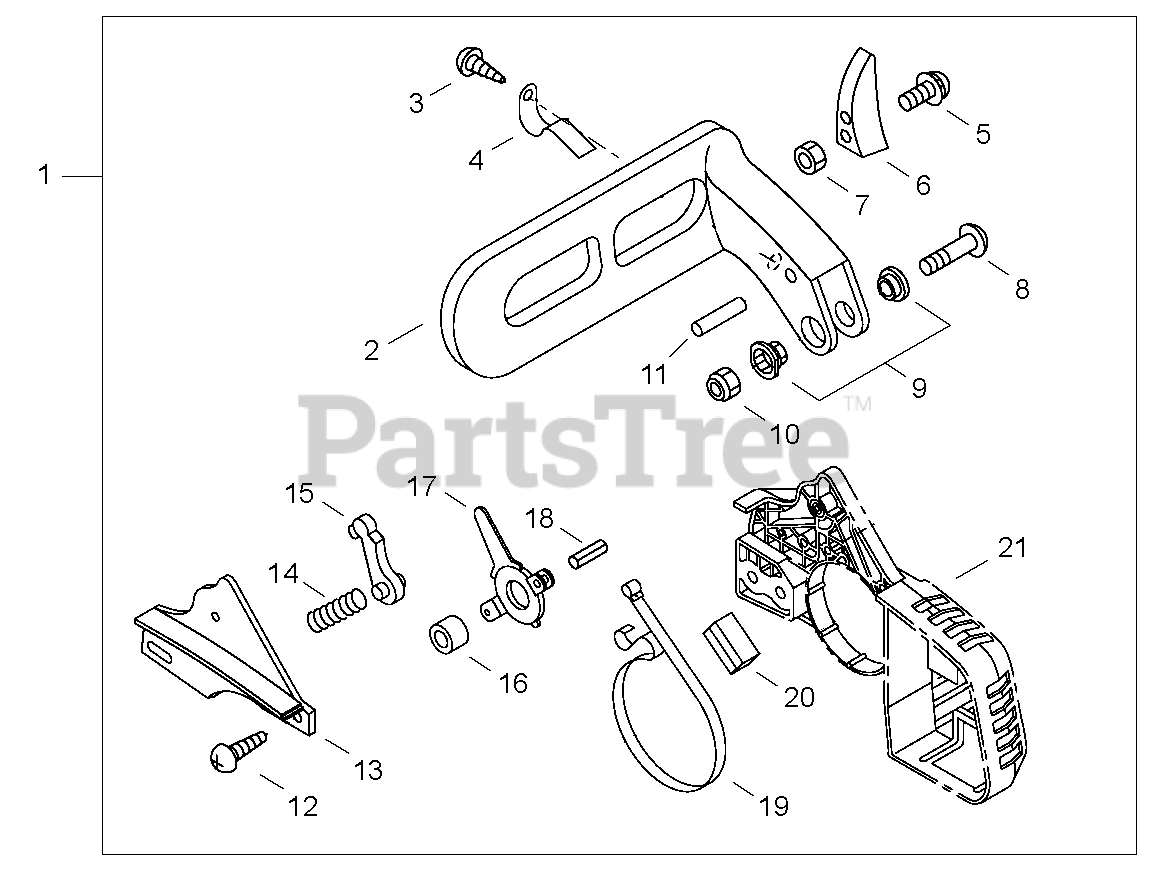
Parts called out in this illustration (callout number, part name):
1	CHAIN BRAKE ASSY
2	LEVER, BRAKE
3	SCREW - 4X10
4	SPRING, RETURN
5	SCREW - 4X20
6	WEIGHT, BRAKE
8	SCREW - 5X32
9	SPACER - 5
10	LOCKNUT - 5
11	ROLLER - 4X23.8
12	SCREW - 4X12 -- TAPPING
13	COVER, BRAKE
14	SPRING, BRAKE
15	STOPPER, BRAKE
16	SPACER - 8
17	LEVER, BRAKE
18	PIN - SPRING -- 4X8
19	BAND, BRAKE
21	COVER, CLUTCH
